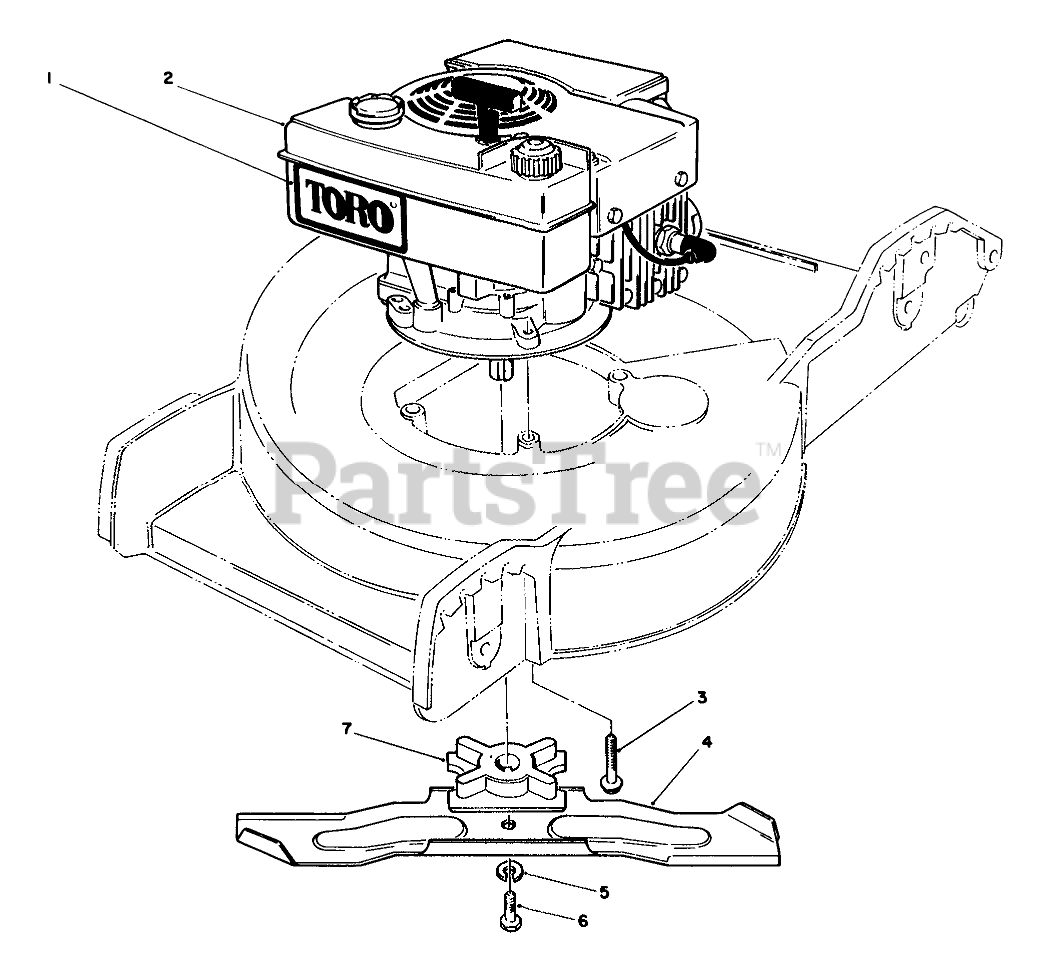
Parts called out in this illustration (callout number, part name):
1	Decal Tow
2	Engine
3	3/8-16 X 2 CAPSCREW
4	Blade
5	WASHER-LOCK
6	SCREW-HH
7	BLADE RETAINER
